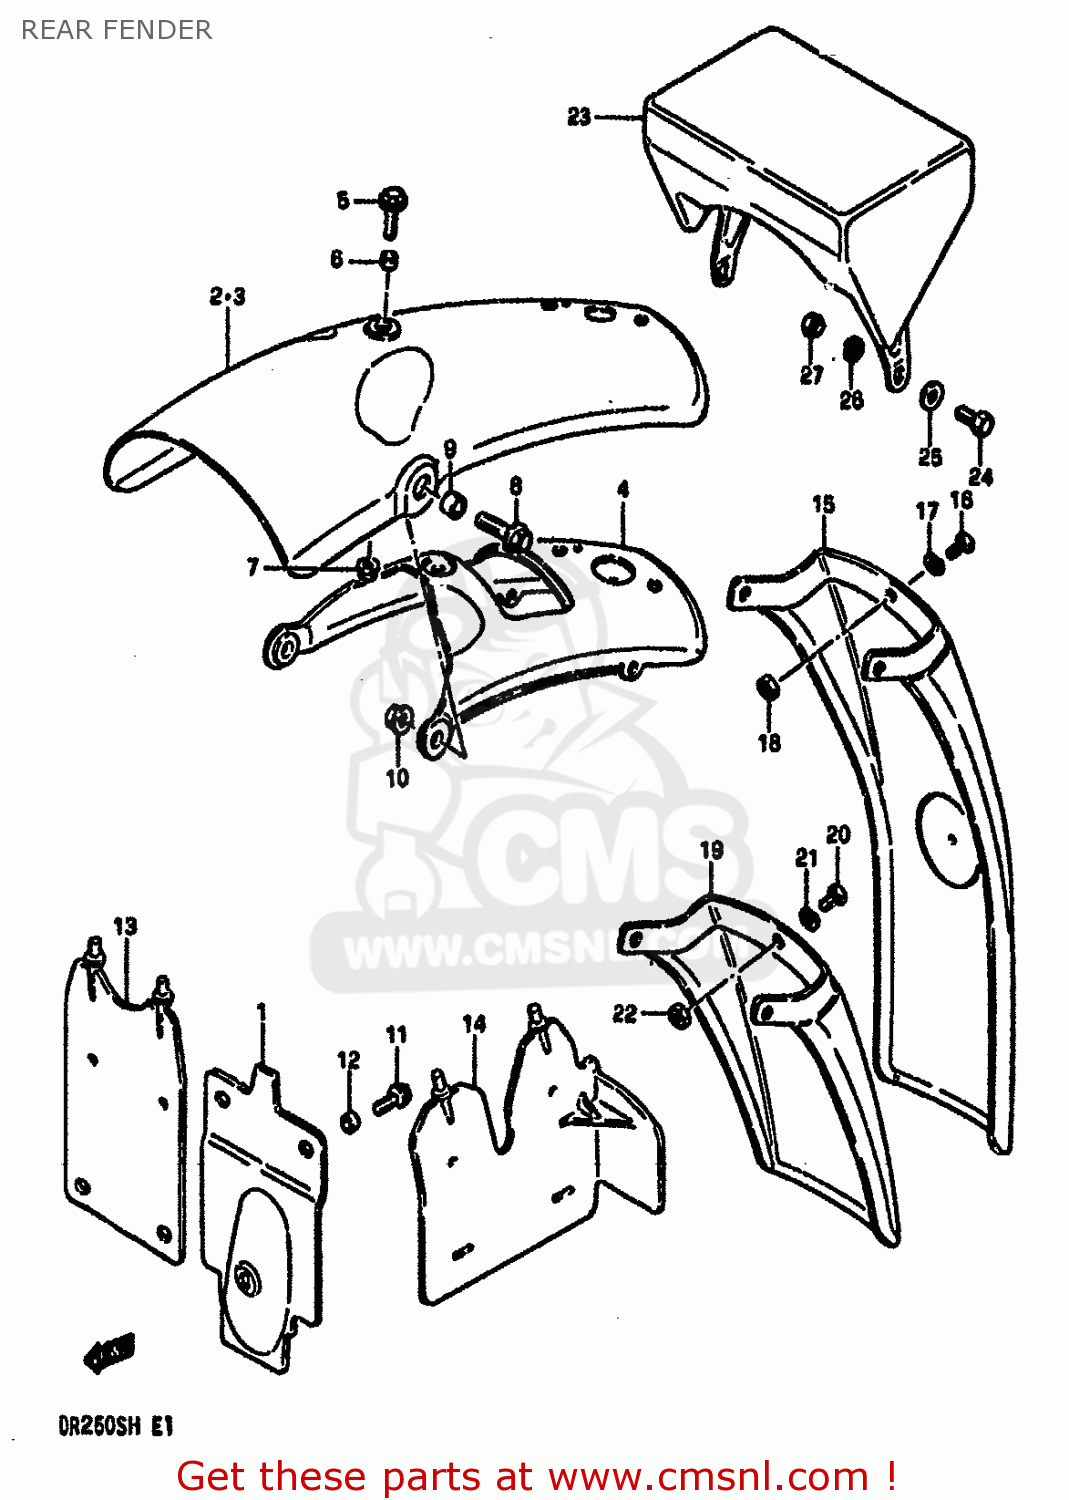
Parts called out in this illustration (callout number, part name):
1	REAR FENDER,FRONT
2	FENDER,REAR (BLUE)
3	FENDER,REAR (BLUE)
4	REINFORCEMENT
5	BOLT
6	SPACER
7	NUT
8	BOLT
9	SPACER(8.2X14X4.5)
10	NUT
11	SCREW, FRONT
12	SPACER
13	MUD GUARD,REAR FENDER
14	MUD GUARD,REAR FENDER,FRONT
15	EXTENSION, REAR FENDER
16	SCREW
17	WASHER,LOCK
18	NUT
19	EXTENSION, REAR FENDER
20	SCREW
21	WASHER,LOCK
22	NUT
23	BAG ASSEMBLY,SEAT TAIL
24	BOLT
25	WASHER
26	WASHER,LOCK
27	NUT
